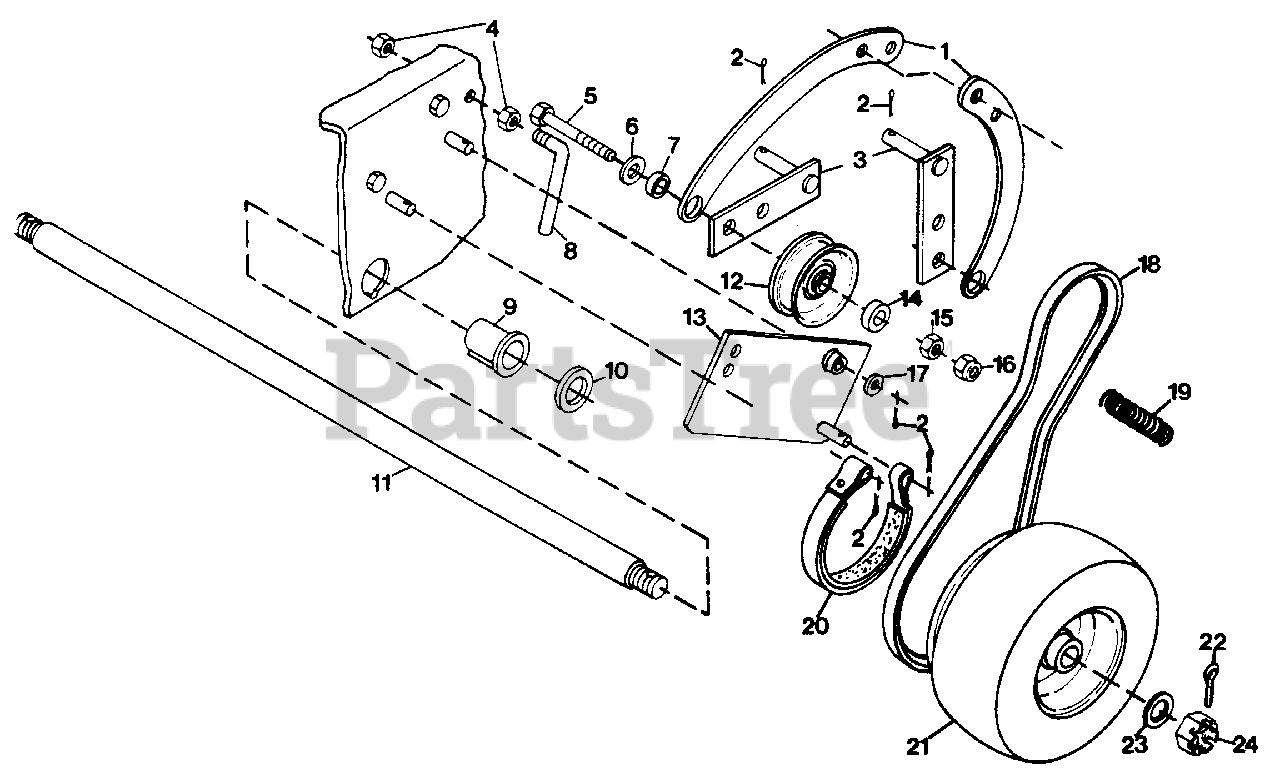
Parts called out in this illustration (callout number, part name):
1	STRAP, WHEEL CLUTCH
2	PIN, COTTER .125X.75
3	WELDMENT, WHEEL CLUTCH L.H.
4	NUT, HEX 1/4-20
5	BOLT, HEX 3/8-16X2.25
6	WASHER, FLAT .406X.812X.065
7	BUSHING, WHEEL CLUTCH
8	ROD, PULLEY CLEANING
9	BUSHING, PRO AXLE
10	SPACER, WHEEL
11	SHAFT, AXLE
11	SHAFT, AXLE (PRO-32)
12	SHEAVE, IDLER
13	WELDMENT, BRAKE LEVER L.H.
13	WELDMENT, BRAKE LEVER R.H.
14	SPACER, IDLER
15	NUT, HEX 3/8-16
16	NUT, LOCK 3/8-16
17	WASHER, FLAT .344X.688X.065
18	BELT, TRACTION
19	SPRING, CLUTCH IDLER
20	ASSEMBLY, BRAKE BAND L.H.
20	ASSEMBLY, BRAKE BAND R.H.
21	ASSEMBLY, PRO WHEEL AND TIRE
21	WHEEL, 13X5.00-6(PRO-32)
22	PIN, COTTER .156X1.50
23	WASHER, FLAT .813X1.37X.100
24	NUT, SLOTTED 3/4-16
